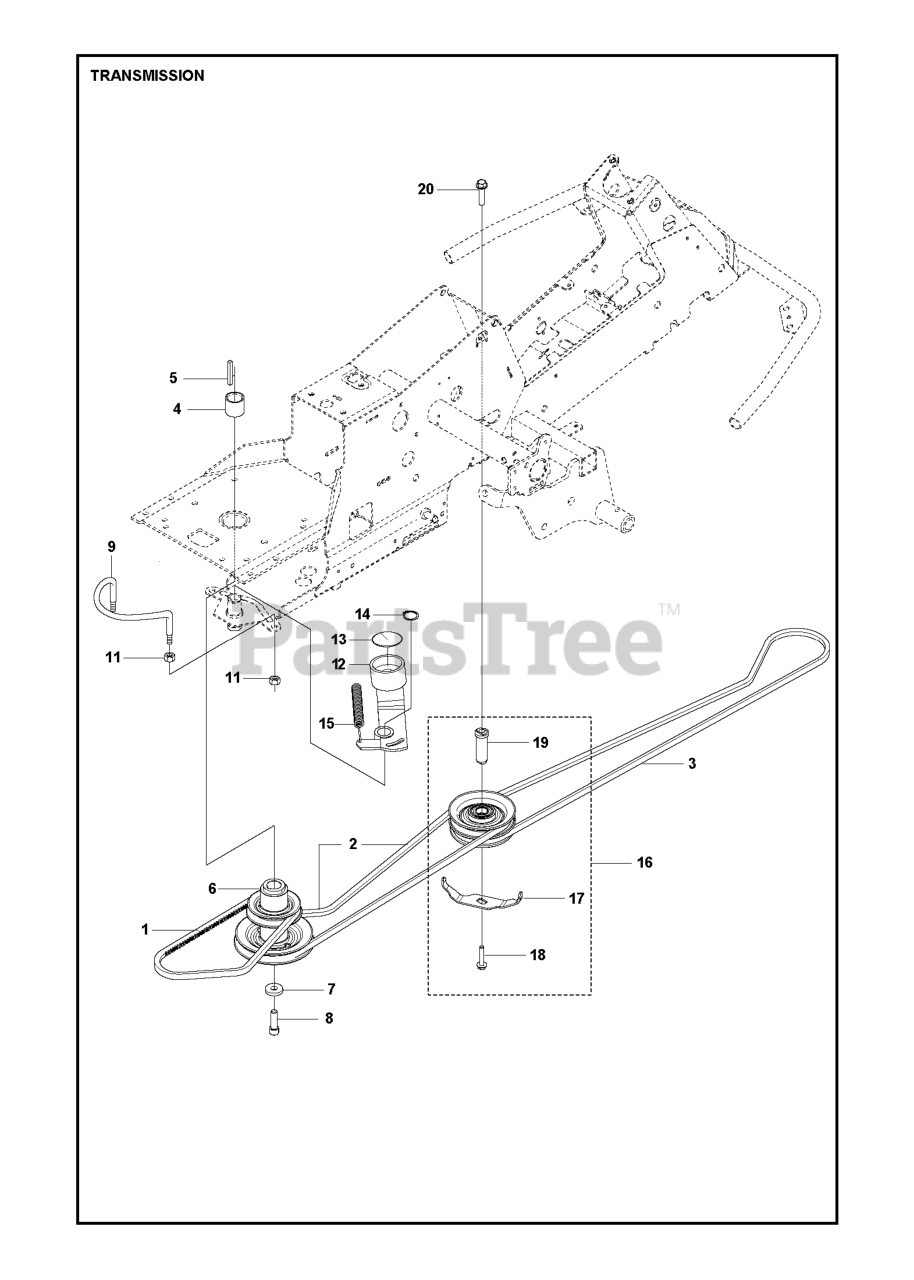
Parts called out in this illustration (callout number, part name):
9	BELT GUIDE
14	RETAINING RING SGA 25
17	BELT GUIDE
